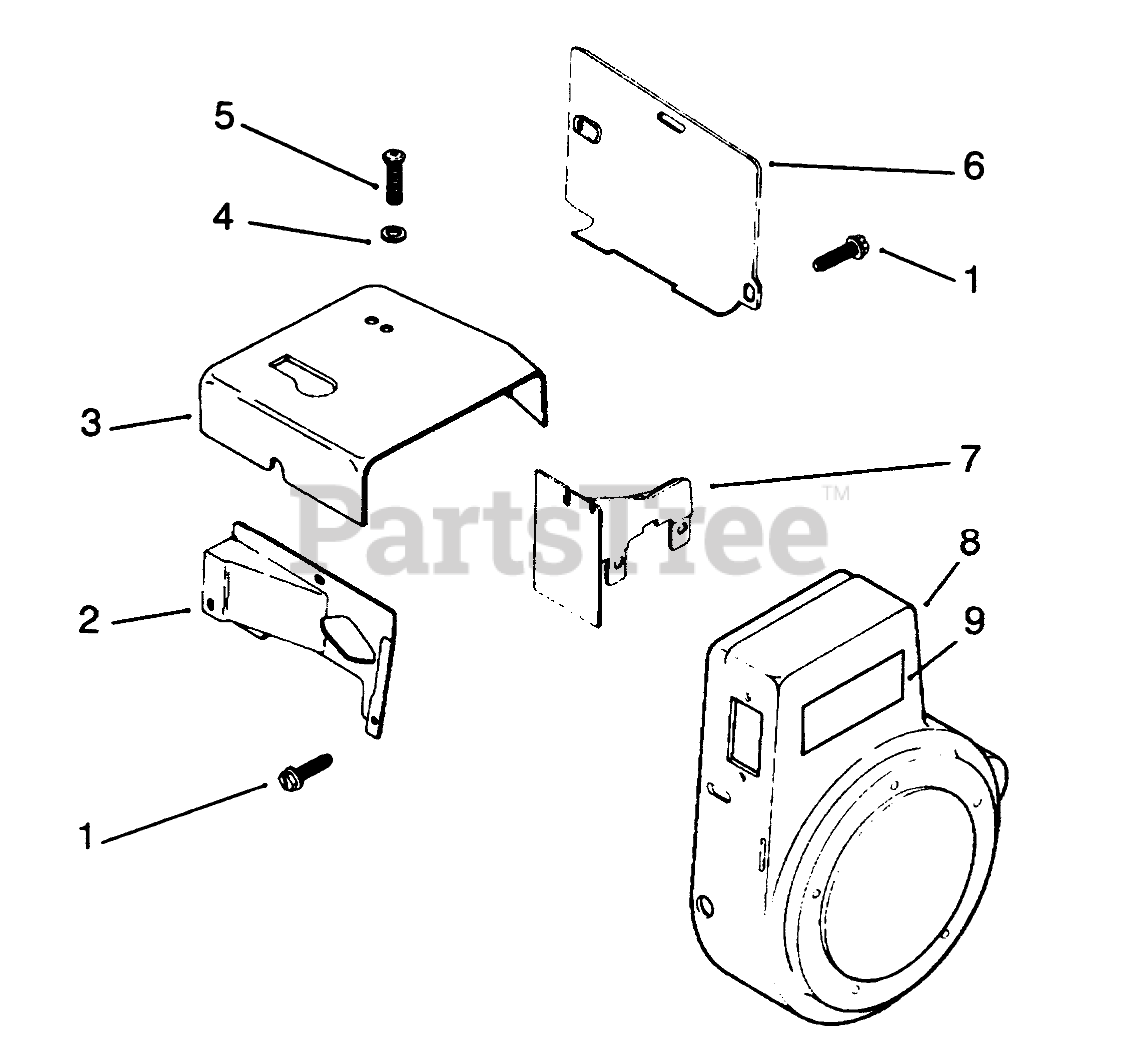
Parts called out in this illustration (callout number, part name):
1	Screw Hex Hd
2	Baffle-SideAir
3	Baffle-Head
4	Washer
5	Screw-Pozidriv T.H.
6	Baffle-Cylinder
7	Baffle-Inner
8	Blower Housing
9	Decal-HP
